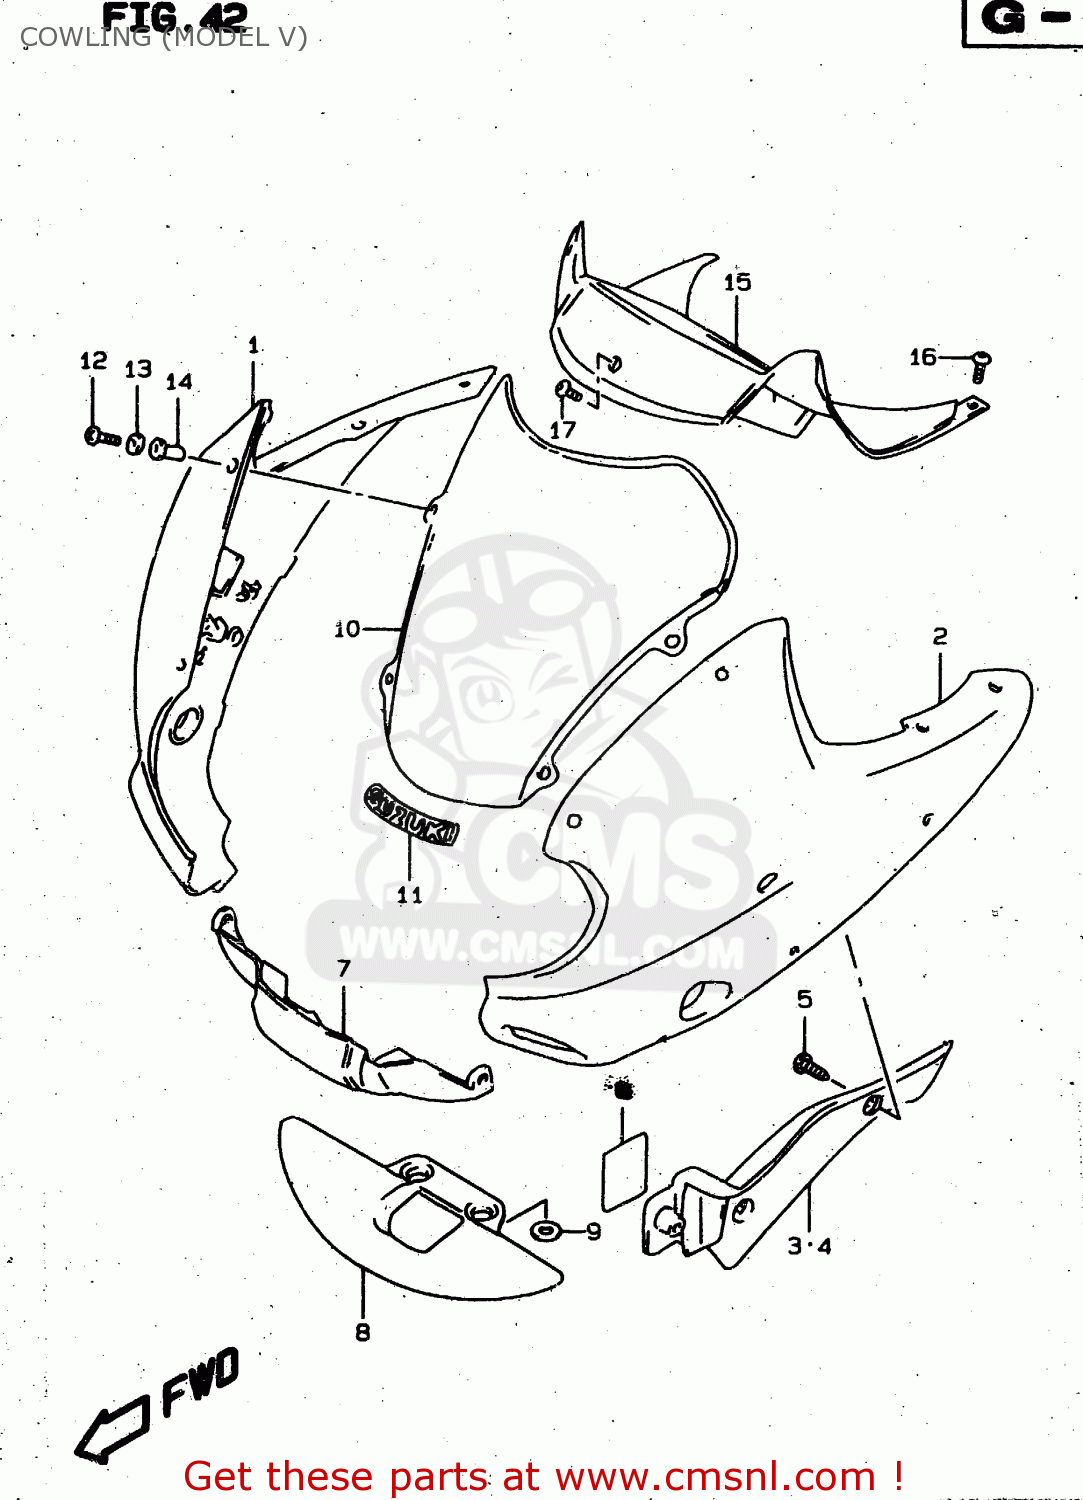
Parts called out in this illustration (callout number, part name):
1	COWLING,SIDE,R
2	COWLING,SIDE,L
3	COVER, SIDE COWL INNER, RH
4	COVER,SIDE COWL INNER,L
5	SCREW 5X10
6	CUSHION(50X42X2.0)
7	COWLING,CTR
8	COVER,COWLING FR LWR
9	WASHER (6.5X18X1.6)
10	WINDSCREEN(GOLD)
11	EMBLEM,SUZUKI
12	SCREW(5X14)
13	WASHER
14	NUT
15	PANEL,METER
16	SCREW(5X10)
17	SCREW(5X12)
